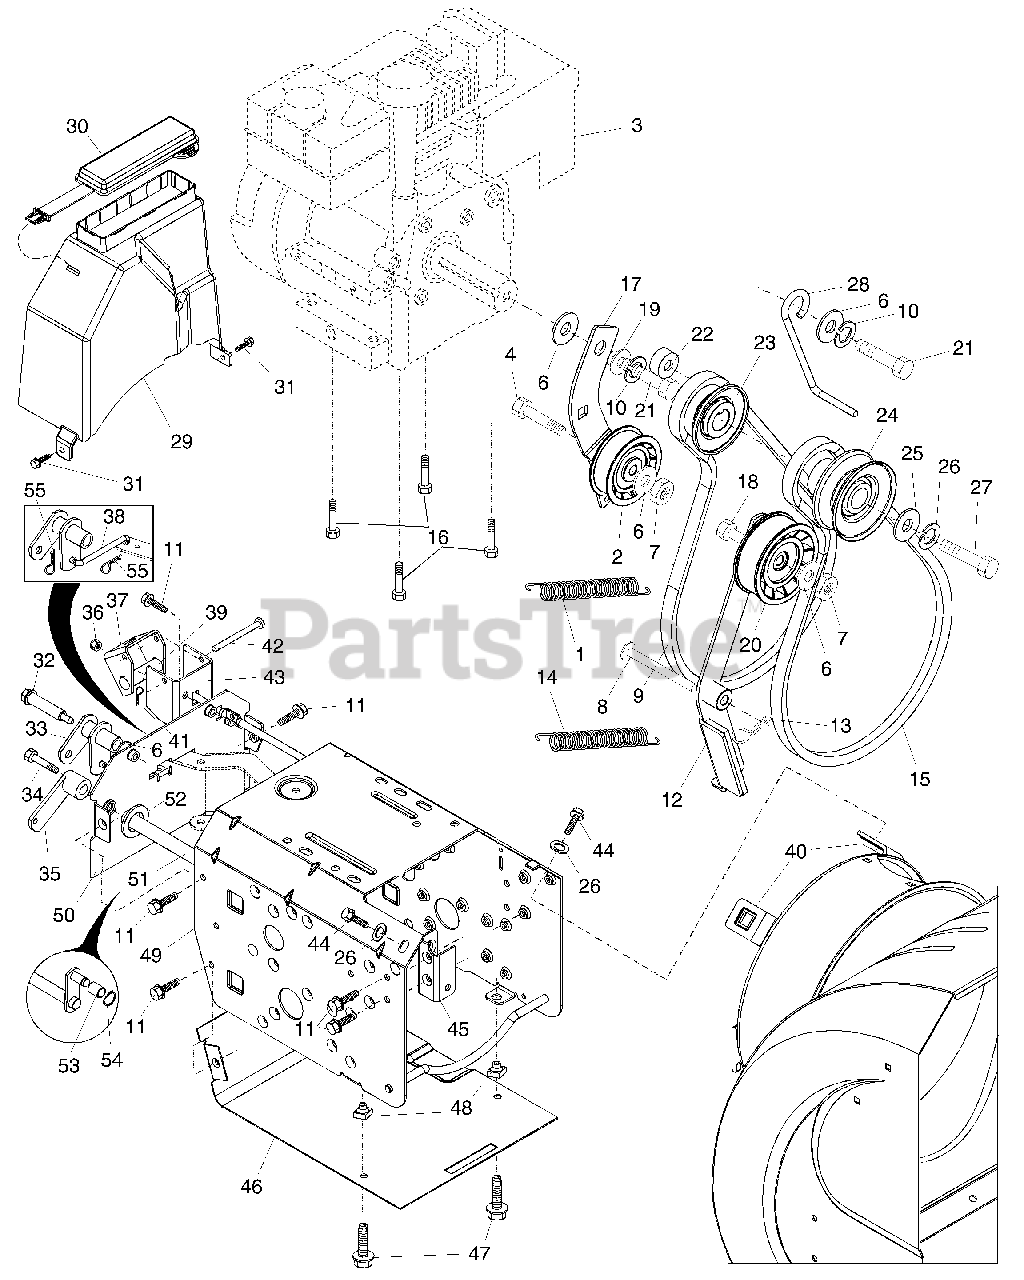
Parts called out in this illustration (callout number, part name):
1	Spring, Traction Idler
2	Pulley, Idler (2-1/4)
4	Screw, Hex Head 5/16-18 x 1-1/4
6	Washer, Flat
7	Nut, Jam, Lock 5/16-18
8	Pin, Idler Pivot
9	V-Belt, Traction Drive
10	Washer, Lock 5/16
11	Screw, Hex Head 5/16-18 x 3/4
12	Arm & Bracket Assembly, Impeller Idler
13	Retainer, Hairpin
14	Spring, Brake
15	V-Belt, Impeller Drive
16	Screw, Hex Head 3/8-16 x 1-1/4
17	Arm, Idler
18	Screw, Hex Head 5/16-18 x 1-1/2
19	Bushing, Idler Pivot
20	Pulley, Idler (2-3/4)
21	Screw, Hex Head 5/16-18 x 1
22	Spacer, Engine Pulley
23	Pulley, Engine, Traction Drive
24	Pulley, Engine, Impeller Drive
25	Washer, Flat 3/8
26	Washer, Lock 3/8
27	Screw, Hex Head 3/8-24 x 1-3/8
28	Guide, Belt
29	Cover, Belt
30	Cover, Toolbox
31	Screw, Hex Head 1/4-20 x 1/2
32	Bolt, Shoulder 5/16-18
33	Bellcrank Shifter
34	Screw, Hex Head 1/4-28 x 3/4
35	Arm, Auger Control
36	Nut, Lock 5/16-18
37	Bellcrank Assembly
38	Link, Speed Control
39	Trunnion, Pivot Bracket
40	Nut, Cage 3/8-16
41	Pin, Cotter 1/16 x 1/2
42	Pin, Pivot Bracket
43	Bracket, Bellcrank
44	Screw, Hex Head 3/8-16 x 1-1/2
45	Arm & Bracket Assembly, Impeller Idler
46	Pan, Frame Bottom
47	Screw, Hex Head 5/16-18 x 3/4
48	Nut, Speed 5/16-18
49	Frame Assembly
50	Plate, Frame End
51	Shaft, Auger Control
52	Washer, Hardened
54	Ring, Retaining
55	Clip, Retainer
